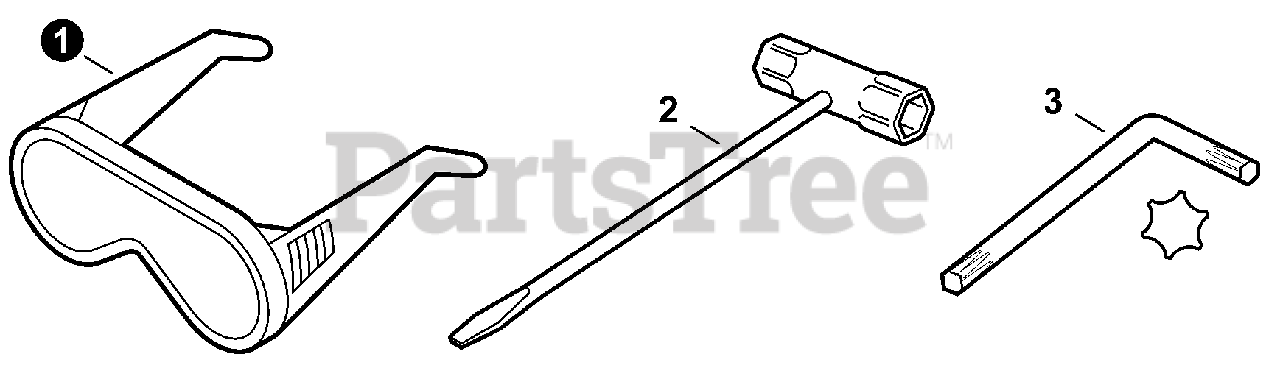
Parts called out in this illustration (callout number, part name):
1	GLASSES, SAFETY
2	T-WRENCH 10x19 MM
3	WRENCH, ALLEN 4 MM
